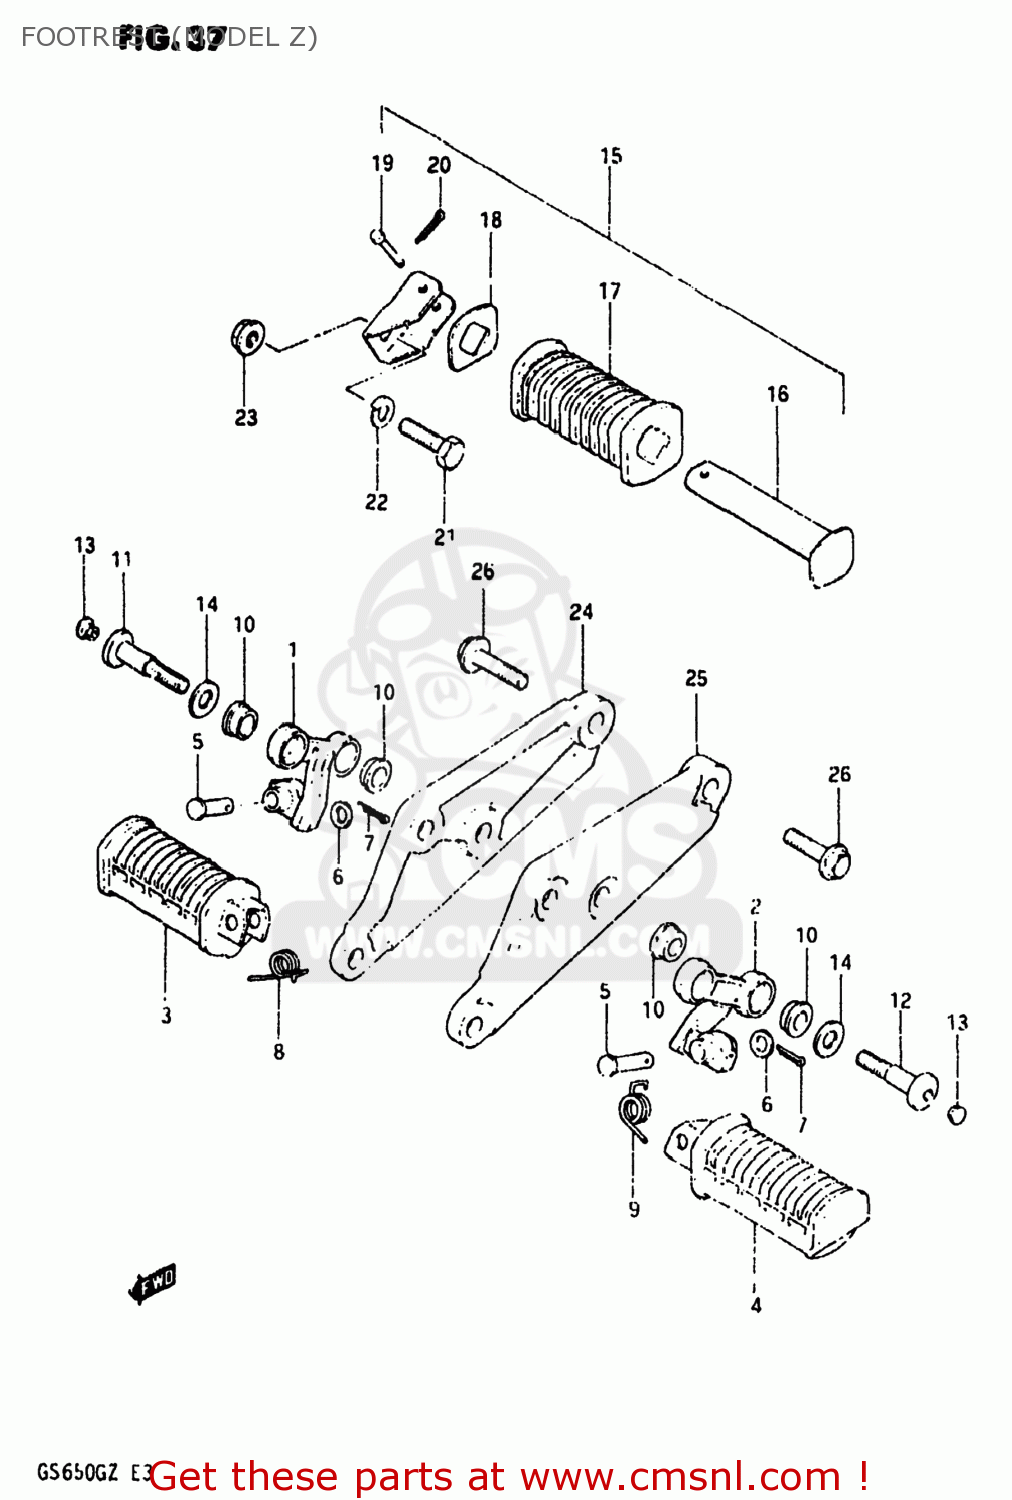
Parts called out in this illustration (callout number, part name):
1	BAR,FRONT FOOTREST,RIGHT
2	BAR,FRONT FOOTREST,LEFT
3	RUBBER,FOOTREST
4	FOOTREST
5	PIN
6	WASHER
7	PIN
8	SPRING
9	SPRING
10	BUSH
11	BOLT
12	BOLT
13	CAP
14	WASHER(10.5X28X2.3)
15	FOOTREST ASSY,PILLION,R
16	BAR,REAR FOOTREST,LEFT
17	RUBBER,PILLION FOOTREST
18	WASHER,FOOTREST RUBBER
19	PIN
20	PIN
21	BOLT,M10X1.25X
22	LOCK WASHER
23	NUT
24	BRACKET,MUFFLER,RIGHT
25	BRACKET,MUFFLER,LEFT
26	BOLT
